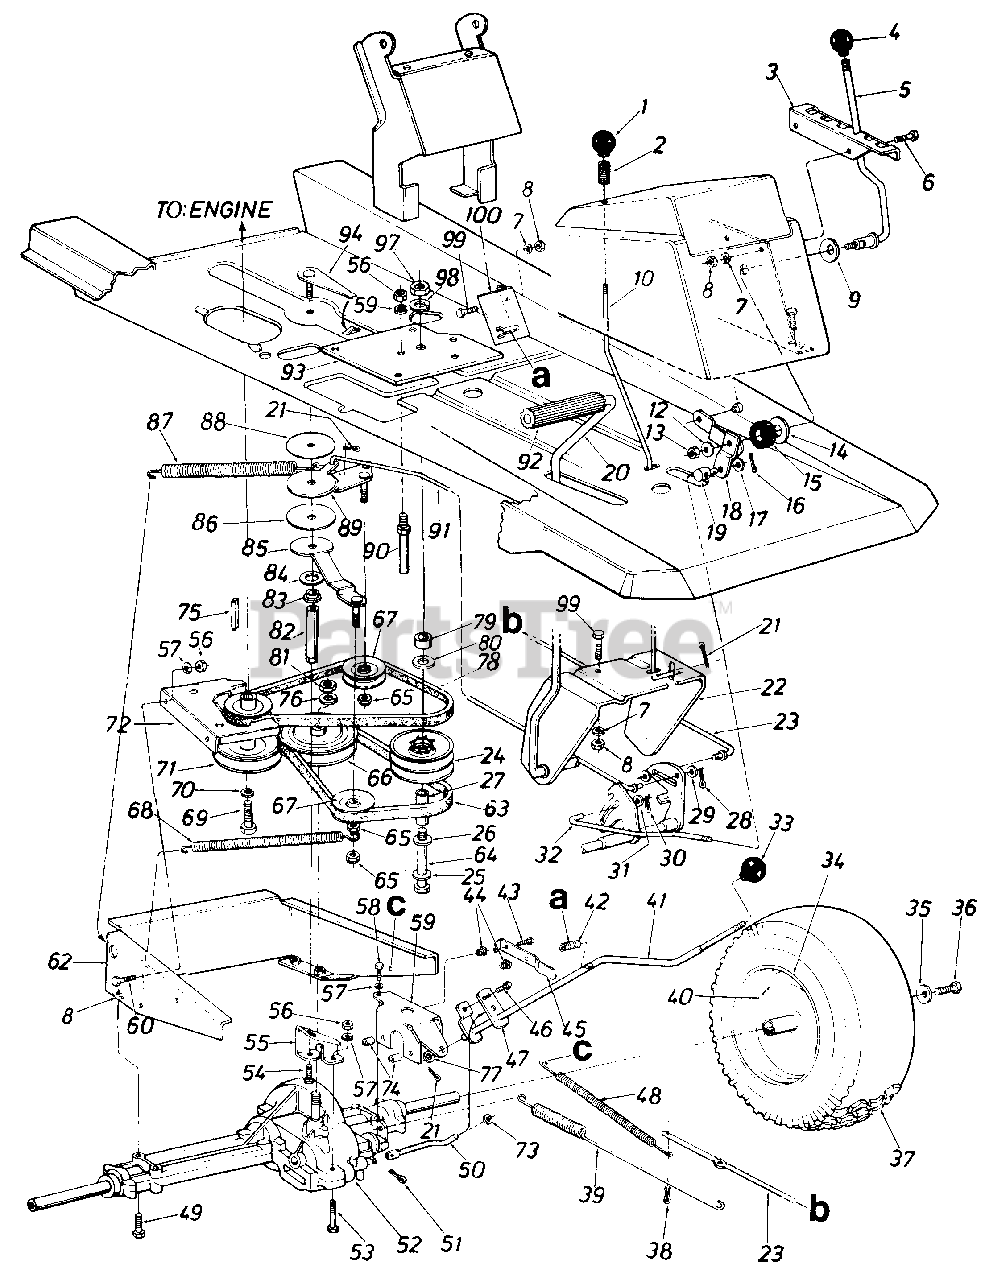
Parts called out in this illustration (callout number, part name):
1	Ball Knob 1/4-20 Thd. 1.25"
2	Compression Spring
5	Speed Control Lever
6	Truss Mach. Scr. 5/16-18 x .75" Lg.
7	L-Wash. 5/16" l.D.
8	Hex Nut 5/16-18 Thd.
9	Bell-Wash. .345" I.D. x .88"
10	Brake Locking Rod
12	Bell-Wash. .345" I.D. x .08"
13	Hex Cent. L-Nut 5/16-18 Thd.
14	Fl-Wash. .50" I.D. x 1.5" O.D.
15	Rubber Washer
16	Intern. Cotter Pin 1/2" Dia.
17	Fl-Wash. 34n l.D. x .68" O.D.
18	Speed Control Lever Brkt. Ass'y.
19	Ferrule-Engagement
20	Clutch/Brake Pedal Ass'y.
21	Cotter Pin 3/32" Dia. x 75"
22	Clutch/Brake Pedal Ass'y.
24	Variable Speed Pulley Ass'y.
25	Washer .635" I.D. x 3.50" O.D.
26	Thrust Brg. 1.25" O.D. x .56" I.D.
27	Spacer Sleeve 2.71"
28	Cotter Pin 1/8" Dia. x 1.25"
29	Fl-Wash. .34" I.D. x .60" O.D.
30	Intern. Cot-Pin 5/16" Dia.
31	Fl-Wash. .34" I.D. x .60" O.D.
32	Speed Control Rod
33	Ball Knob
35	Bell-Wash. .345" I.D. x .88"
36	Hex L-Bolt 5/16-24 x .75" Lg.
38	Cotter Pin 1/8" Dia. x 1.25"
39	Extension Spring 17.0" Lg.
40	Air Valve
43	C Sink AB S-Tap Scr. #8 x 50n Lg
44	Push-in Nut #10
45	Spring Switch
46	Hex Bolt 1/4-20 x .50" Lg.
47	Shift Lever Adjusting Link
48	Ext. Spring 81/4" Lg.
49	3/16-18 x 2.50 Hex Bolt
51	Intern. Cotter Pin
52	Transaxle
53	Hex Bolt 1/4-20 x 1.75" Lg.
54	Hex Bolt 3/8-24 x .75" Lg.
55	Torque Rod Bracket
56	Hex Nut 1/4-20 Thd.
57	L-Wash. 1/4" I.D.
58	Self-Tap Mach. Scr. Type "C" 1/4-20 x 1.37" Lg.
59	Shift Lever Support Brkt.
60	Hex Bolt 1/4-20 x l.OOn Lg.
62	Transaxle Support Ass'y.
63	V-Belt
64	Hex Bolt 3/8-16 x 4.5" Lg.
65	Hex Ins. L-Nut 3/8-24 Thd.
66	5/8 V-Pulley .500" l.D. x 6"
67	V-Belt Idler .38" I.D. x 3.06"
68	Ext. Spring .50" O.D. x 6.37"
69	Hex Bolt 7/16-20 x 1.00n Lg.
70	L-Wash. 7/16" l.D.
71	Engine Pulley .500" O.D. & 3.56" O.D.
72	Upper Eng. Belt Guard
74	Spacer .256" I.D. x .5" O.D>
75	Sq.-Key 1/4" x 2.00n Lg.
76	L-Wash. 1/2" I.D.
77	Fl-Wash. .469" I.D. x .88"
78	V-Belt
79	Spacer 1.00n x .380" O.D.
80	Teflon Washer .565 I.D. x .12 O.D.
81	Hex Nut 1/2-20 Thd.
83	Flange Bearing .378
84	Fl-Wash. .640" I.D. x 1.24"
85	Idler Bracket Ass'y.
86	Thrust Wash. .635" I.D.
87	Extension Spring 7.58n Lg.
88	Thrust Wash. .385" I.D.
89	Idler Bracket Ass'y. For Clutch
90	Belt Guard Pin 1/4" Dia.
92	Foot Pad
93	Mtg. Brkt. Variable Pulley
98	L-Wash. 3/8 Heavy Duty
99	Hex Bolt 5/16-18 x .75" Lg.
100	Shift Lever Spring Brkt.
